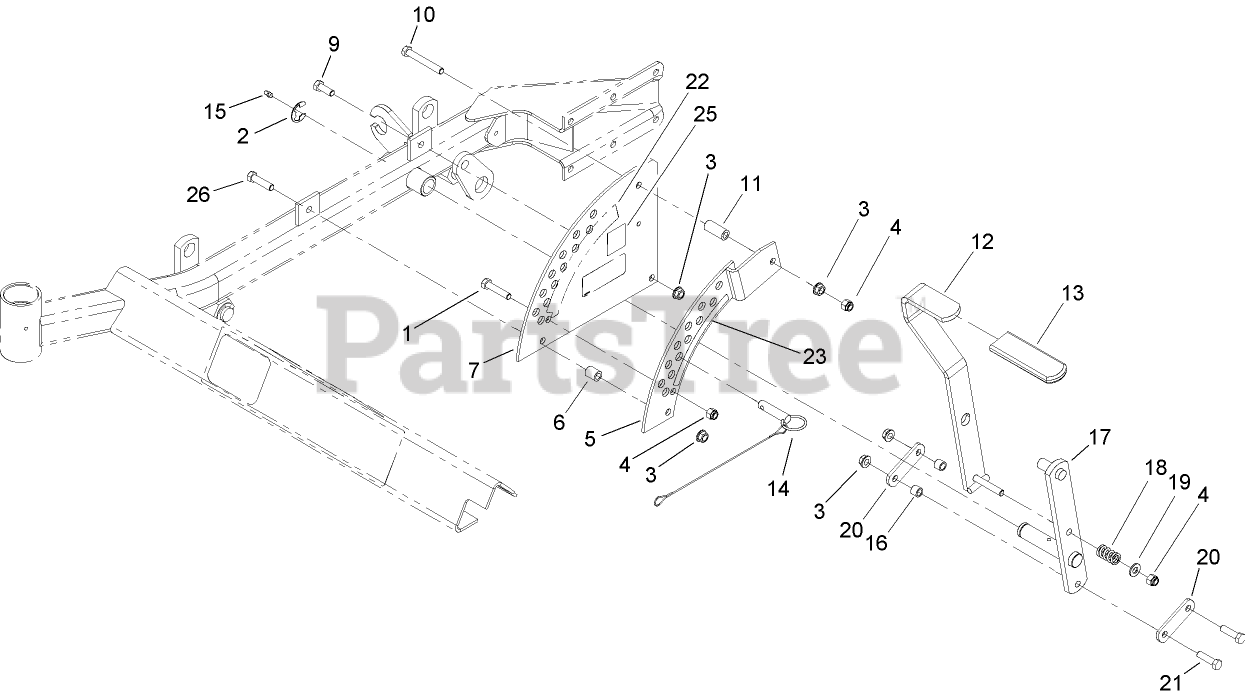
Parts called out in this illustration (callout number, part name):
1	SCREW-HH
2	RING-RETAINING, EXT
3	NUT-HHF, WHIZ
4	NUT-LOCK, NI
5	PLATE-LIFT, DECK
6	BUSHING-LEVER, LIFT
7	PLATE-LIFT, DECK
9	SCREW-HH
10	SCREW-HH
11	BUSHING-LEVER, LIFT
12	HANDLE-LIFT
13	GRIP-LEVER, LIFT
14	Hitch Pin ASM
15	FITTING-GREASE
16	Bushing
17	LIFT ARM ASM
18	SPRING-COMPRESSION
19	WASHER-FLAT
20	ARM-LIFT, DECK
21	SCREW-HH
22	DECAL-DECK HEIGHT, OUTER
23	DECAL-DECK HEIGHT, INNER
25	DECAL-NOISE
26	SCREW-HH
